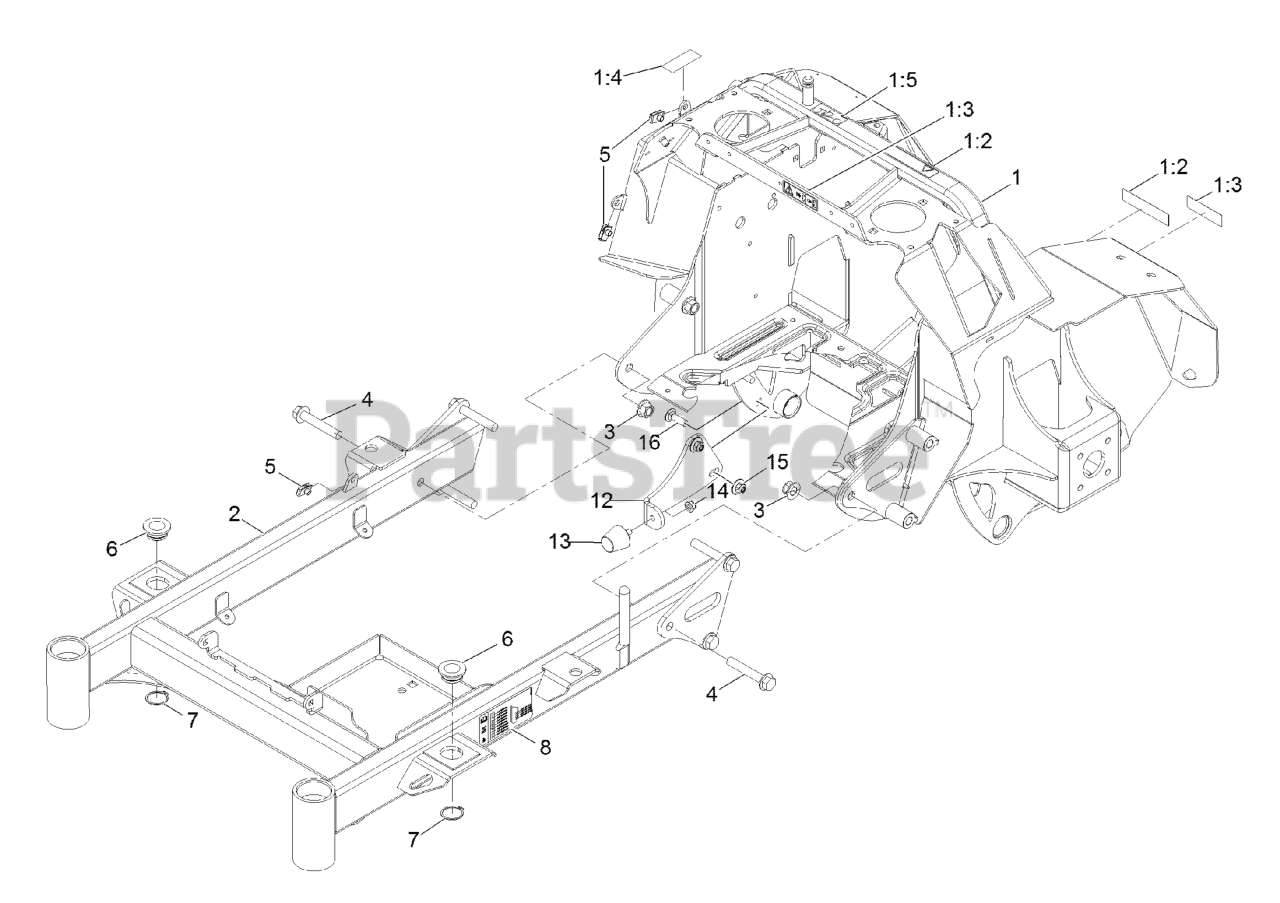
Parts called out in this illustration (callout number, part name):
1	ASM-FRAME
1:2	DECAL-WARNING
1:3	DECAL, COVER MISSING
1:4	DECAL-BRAKE, PARKING
1:5	DECAL-BELT ROUTING HYD
2	ASM-FRT FRAME 32/36
3	Nut-Lock 1/2-13
4	SCREW-HF
6	BUSHING-DECK
7	RING-RETAINING
8	DECAL-HEIGHT OF CUT SM
12	BRACKET-BUMPER 32
13	BUMPER-RUBBER
14	NUT-HF, NI
15	Nut-Nyloc 3/8-16 Flg
16	BOLT-CARR
